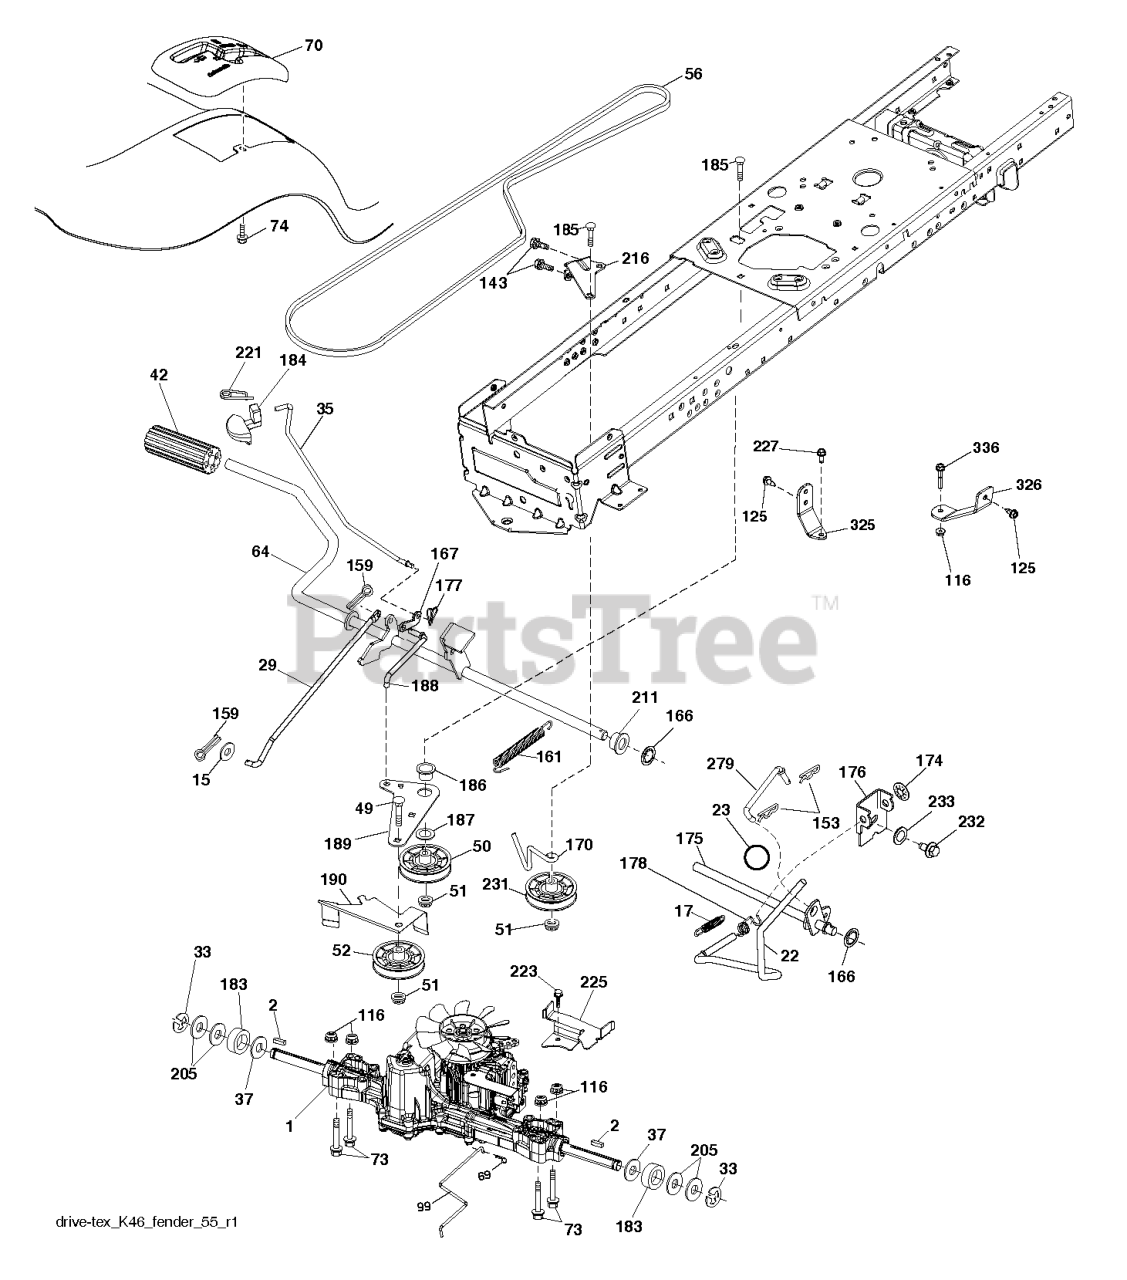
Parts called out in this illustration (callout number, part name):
1	DECK W/DECALS 52" HUS WSL
2	HCS 1/2C X 3 1/4
3	PULLEY 52" DECK
4	BLADE OEM 18"
5	NUT 5/16 NYLOC
6	ANTI-SCALP ROLLER
8	WASHER 3/8 FLAT
9	NUT 3/8-16 NYLOC
10	DECK BELT - 52"
11	HCS 3/8C X 3 1/2
12	HCS 5/16C X 1 1/4
13	DISCHARGE CHUTE ORANGE
14	BELT SHIELD
15	SPINDLE WASHER
16	KEY 1/4 SQ X 1 1/8
17	LIFT CHAIN
18	DECK SPRING
19	IDLER PULLEY
20	IDLER PULLEY (TALL)
21	IDLER BUSHING
22	NUT 7/16C WHIZ
23	SCREW 3/8C X 2 3/4 HEX CAP
24	NUT 7/16C CENTERLOCK
25	HCS 5/8F X 1 1/4
26	LOCKWASHER 5/8
27	WASHER 7/16 LOCK
28	HCS 7/16F X 1 1/2
29	BELT SHIELD
30	NUT 5/16C CENTERLOCK
32	SUPPORT PLATE
33	CENTER BAFFLE - 52"
34	MAIN BAFFLE 52"
35	CARRIAGE BOLT 5/16C X 5/8"
36	WASHER 5/16 FLAT
37	HCS 7/16C X 1 1/2
38	4CS 3/8C X 1 SERRATED HEAD
39	WASHER 3/8 FLAT
40	NUT 1/2-13 HEX NYLOC ZD
41	WASHER 1/2 FLAT
42	IDLER PULLEY
43	ZERK
45	PIVOT BUSHING
46	WASHER, SUPPORT
47	HOUSING ASSEMBLY
49	COMBO SPACER
50	BUSHING.MACHINE.18.GAUGE
51	BEARING
53	HOUSING, DIE CAST
